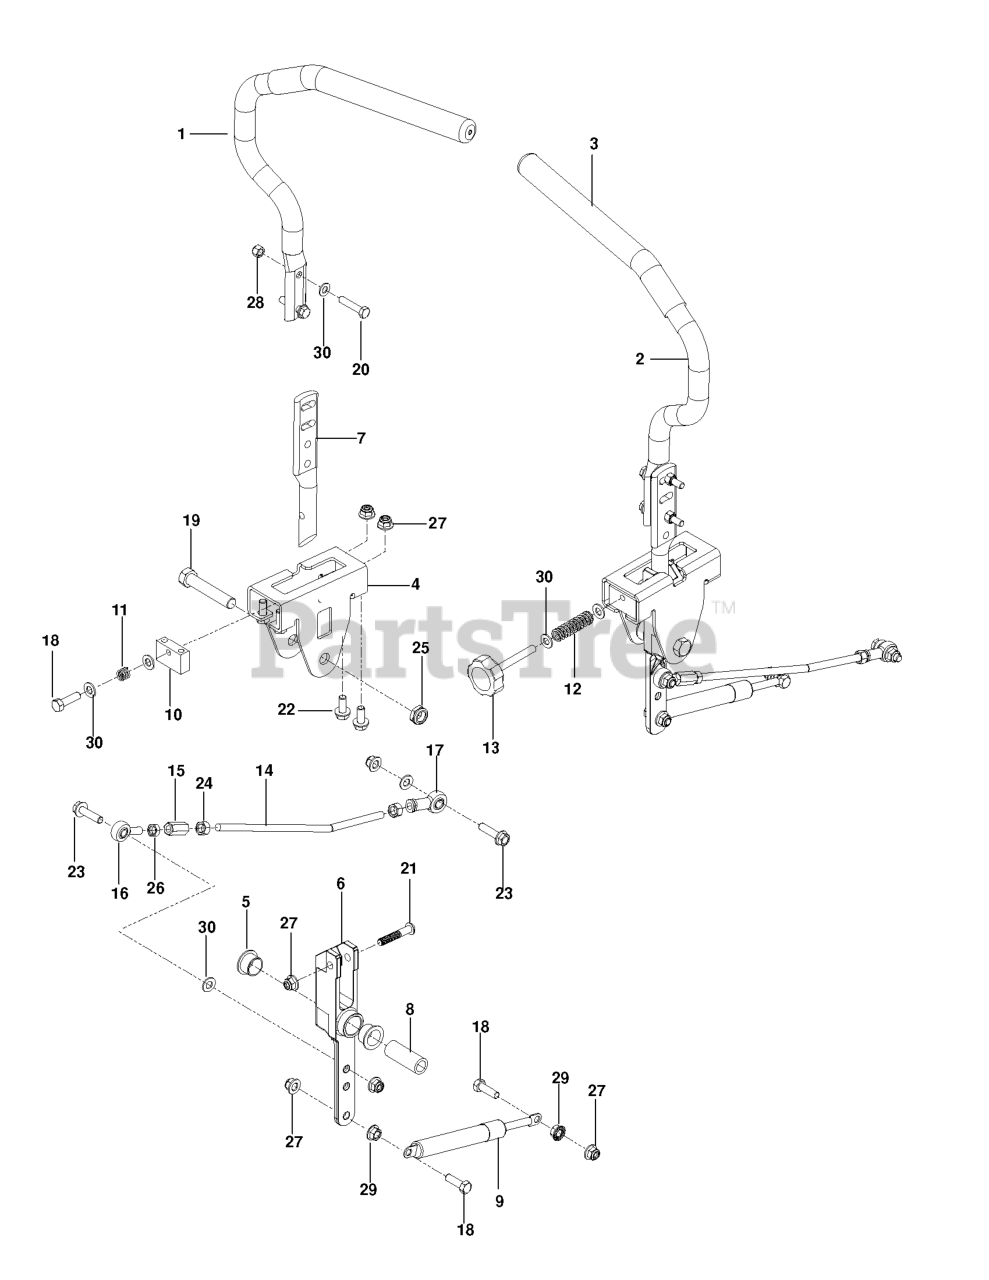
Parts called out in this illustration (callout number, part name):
1	LEVER.DRIVE.W/GRIP.RIGHT
2	LEVER.DRIVE.W/GRIP.LEFT
3	GRIP - DRIVE LEVER 12"
4	BRACKET, CONTROL
5	BEARING, FLANGE
6	LEVER CONTROL PIVOT
7	LEVER.HANDLE MOUNT
8	SPACER, PIVOT CONTROL
10	BLOCK.TRACKING
12	SPRING COMPRESSION 2.0
13	KNOB
14	ROD, CONTROL
15	ROD END COUPLER
16	RP.ROD.END.LH
17	RH ROD END
18	HCS 5/16C X 1 1/4
19	HCS 1/2C X 2 3/4
20	CAPSCREW 5/16 X 1/1/2 HEX HEAD
21	SCREW 5/16-18 X 1 3/4 BTN-HD
22	HHFS 5/16-18 X 3/4
23	HHFS 5/16-18 X 1.25 TPBLT GD 5
25	NUT 1/2-13 HEX JM NYL
26	NUT 5/16F LEFTHAND
27	5/16-18 NYLOC FLANGE NUT
28	NUT 5/16 NYLOC
29	NUT 5/16C WHIZ
30	FLAT WASHER 5/16 SAE
